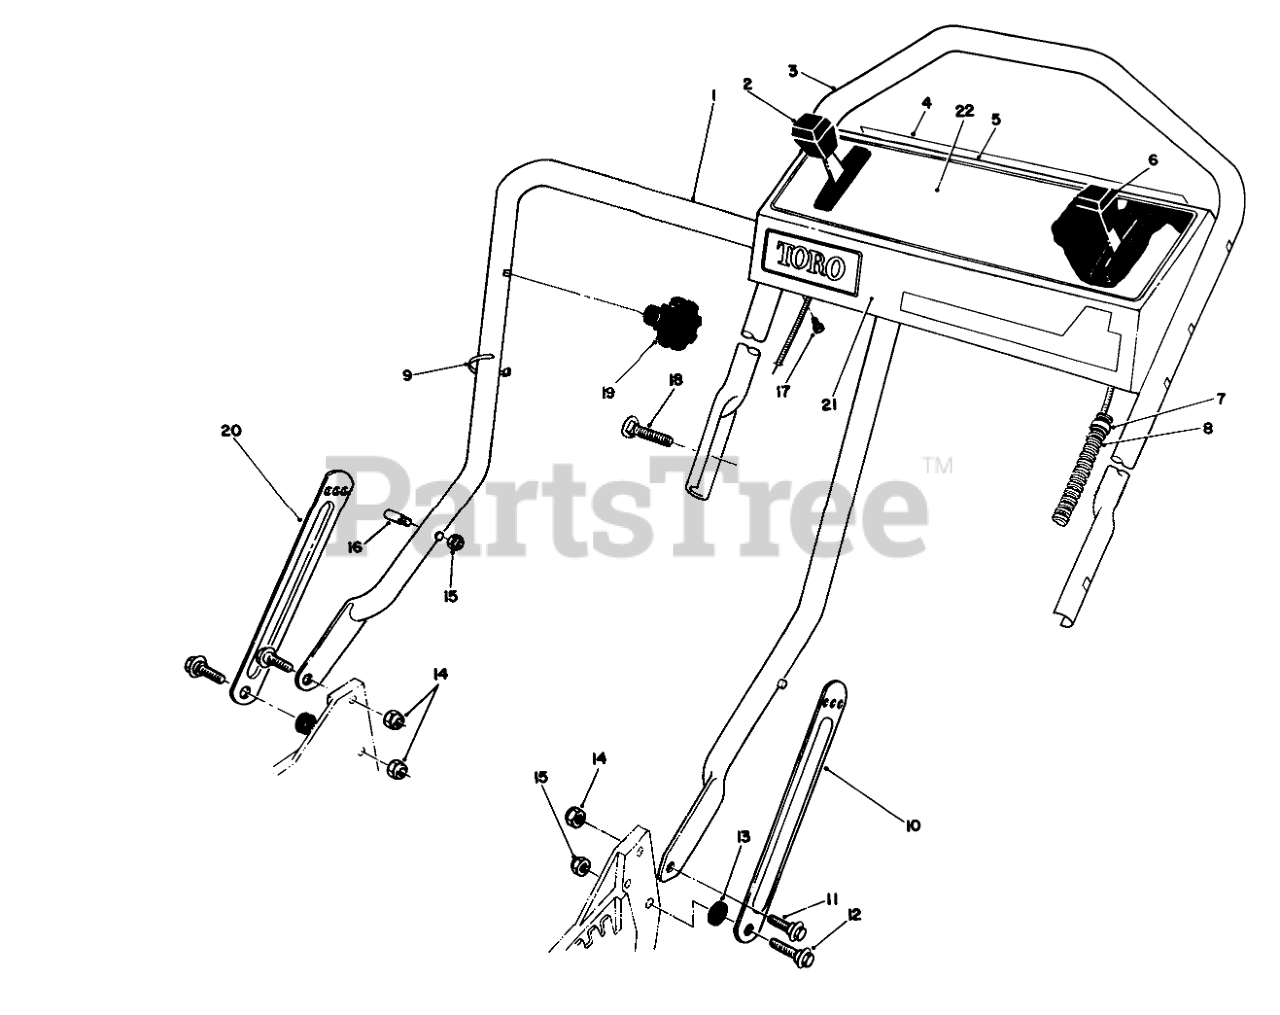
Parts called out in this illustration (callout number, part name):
1	LOWER HANDLE ASM
2	Control-Ground Speed
3	UPPER HANDLE, PVC DIP
4	DECAL - PANEL, REAR
5	Panel-Control (Incl. Ref. #4 &22)
6	THROTTLE CONTROL
7	FITTING-RING
8	CONTROL CABLE COVER
9	TIE-CABLE
10	LH HANDLE LATCH
11	SCREW-SHOULDER
12	SCREW-SHOULDER
13	SPACER
14	NUT-LOCK, NI
15	NUT-LOCK, NI
16	HANDLE PIN
17	SCREW-HWHTF
18	5/16-18 X 2 HNDLE SCREW
20	RH HANDLE LATCH
21	DECAL - TORO
22	DECAL - INSTRUCTION
